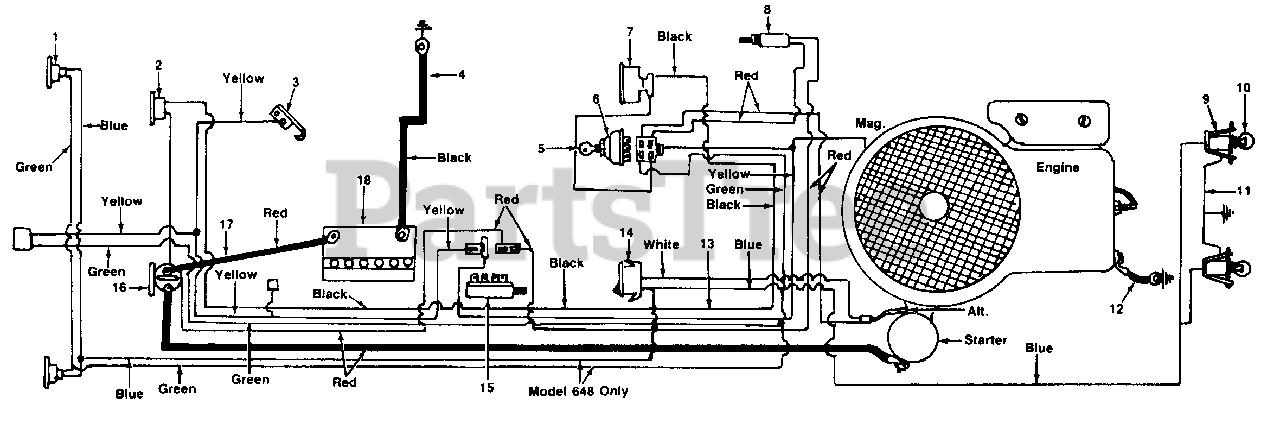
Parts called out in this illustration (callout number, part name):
1	Taillight
2	Circuit Breaker
3	Spring Switch
4	Ground Wire 9.0" Lg.
5	Ignition Key
6	Ignition Switch
7	Ammeter
8	Safety Switch
9	Socket Headlight
10	Lamp Headlight
11	Grounding Wire
12	Ground Wire 7.25" Lg.
13	Wire Harness
14	Light Switch
15	Safety Switch
16	Solenoid
17	Elec. Wire w/Bolt
18	12-V Battery
